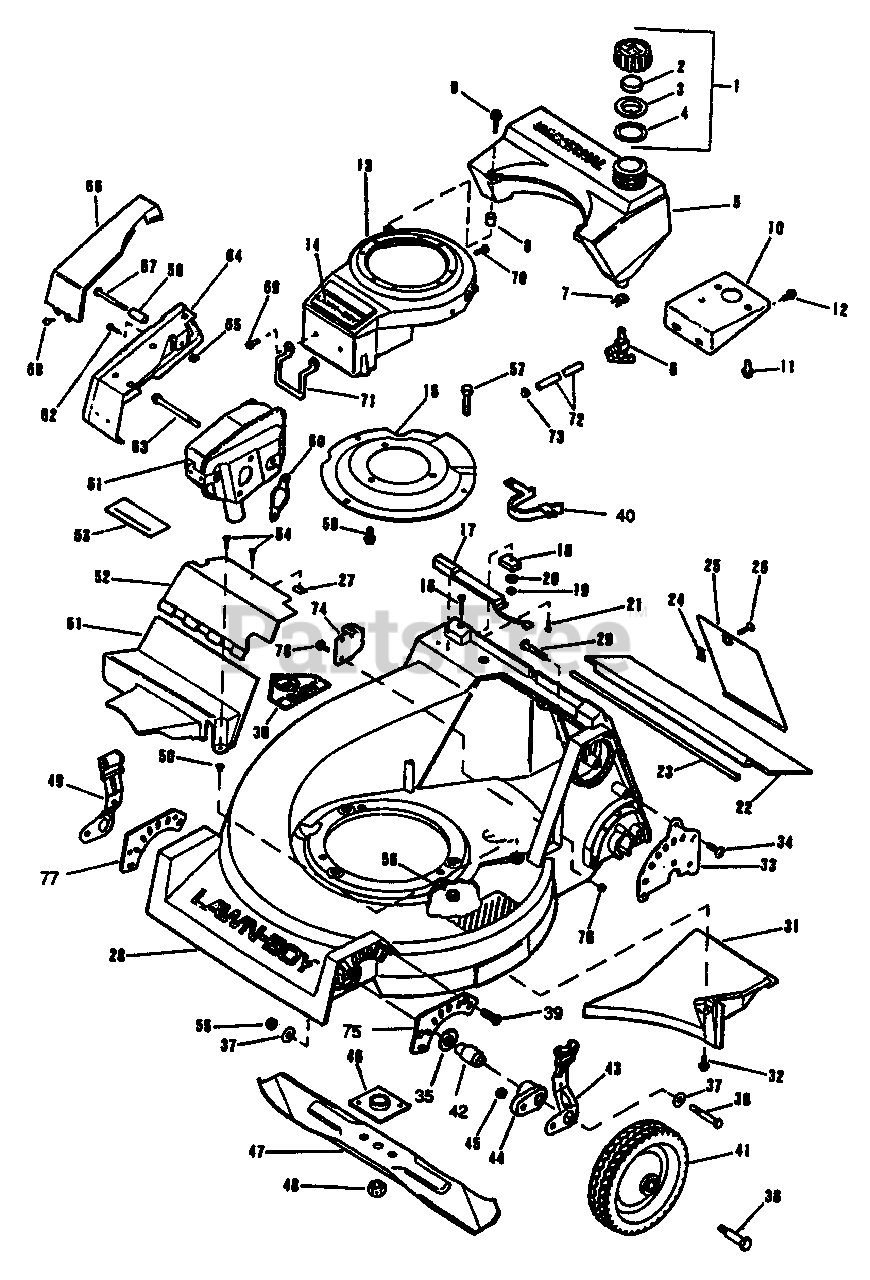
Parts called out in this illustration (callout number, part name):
1	Fuel Cap Assy (Inc. 2-4)
2	Baffle
3	Baffle-Cover
4	Gasket
5	Fuel Tank
6	Valve and Screen
7	Clamp
8	Spacer
9	Screw-Fuel Tank to Shroud
10	Fuel Tank Mounting Bracket
11	Screw-Fuel Tank to Bracket
12	Screw-Tank Bracket to Block
13	Shroud & Applique Assy (Inc. 14)
14	Applique
15	Engine Mtg. Plate
16	Screw-Magnet to Housing
17	Bag Interlock Switch
18	Magnet
19	Nut-Magnet to Housing
20	Lockwasher-Magnet to Hsg
21	Screw-Interlock Switch to Hsg
22	Trailing Shield
23	Trailing Shield Pivot Rod
24	Speed Nut
25	Access Door
26	Screw-Access Door to Hsg
27	Speed Nut
28	Housing Assy (Inc. 29-32)
29	Handle Mounting Bolt
30	Decal-Blade Contact Warning
31	Baffle-Chute Floor
32	Screw-Baffle to Housing
33	Height Adjust Plate
34	Screw-Plate to Housing
35	Flat Washer
36	Screw-Front Height Adjust Arm
37	Washer-Front Height Adjust Arm
38	Shoulder Bolt-Front Wheel
39	Flat Head Screw
40	Belt Guide-Engine
41	Wheel & Tire Assy
42	Front Height Adjust Bushing
43	Knob & Spring Assy-Front L.H.
44	Front Height Adjust Arm
45	Nut-Front Wheel Bolt
46	Collar and Plate
47	21" Blade
48	Locknut-Blade
49	Knob & Spring Assy-Front R.H.
50	Grommet
51	Lower Drive Cover
52	Upper Drive Cvr w/Decal (Inc. 53)
53	Decal-Warning
54	Screw-Drive Cover to Housing
55	Nut-Height Adjust Arm
56	Locknut-Mting Plate to Housing
57	Screw-Mting Plate to Housing
58	Spacer-Muffler Guard
59	Screw-Mounting Plate to Engine
60	Exhaust Gasket
61	Muffler
62	Screw-Muffler Guard
63	Screw-Muffler
64	Muffler Guard Assy (Inc. 65-66)
65	Pushnut
66	Muffler Cover
67	Screw-Muffler Guard
68	Screw-Muffler Guard
69	Hex Flange Head Screw
70	Screw-Shroud to Engine
71	Spark Plug Guard
72	Fuel Line
73	Clamp-Fuel Line to Carburetor
74	Cable Anchor
75	Front Height Adj. Plate-LH.
76	Locknut-Cable Anchor to Hsg
77	Front Height Adj. Plate-R.H.
78	Screw-Cable Bracket to Hsg
